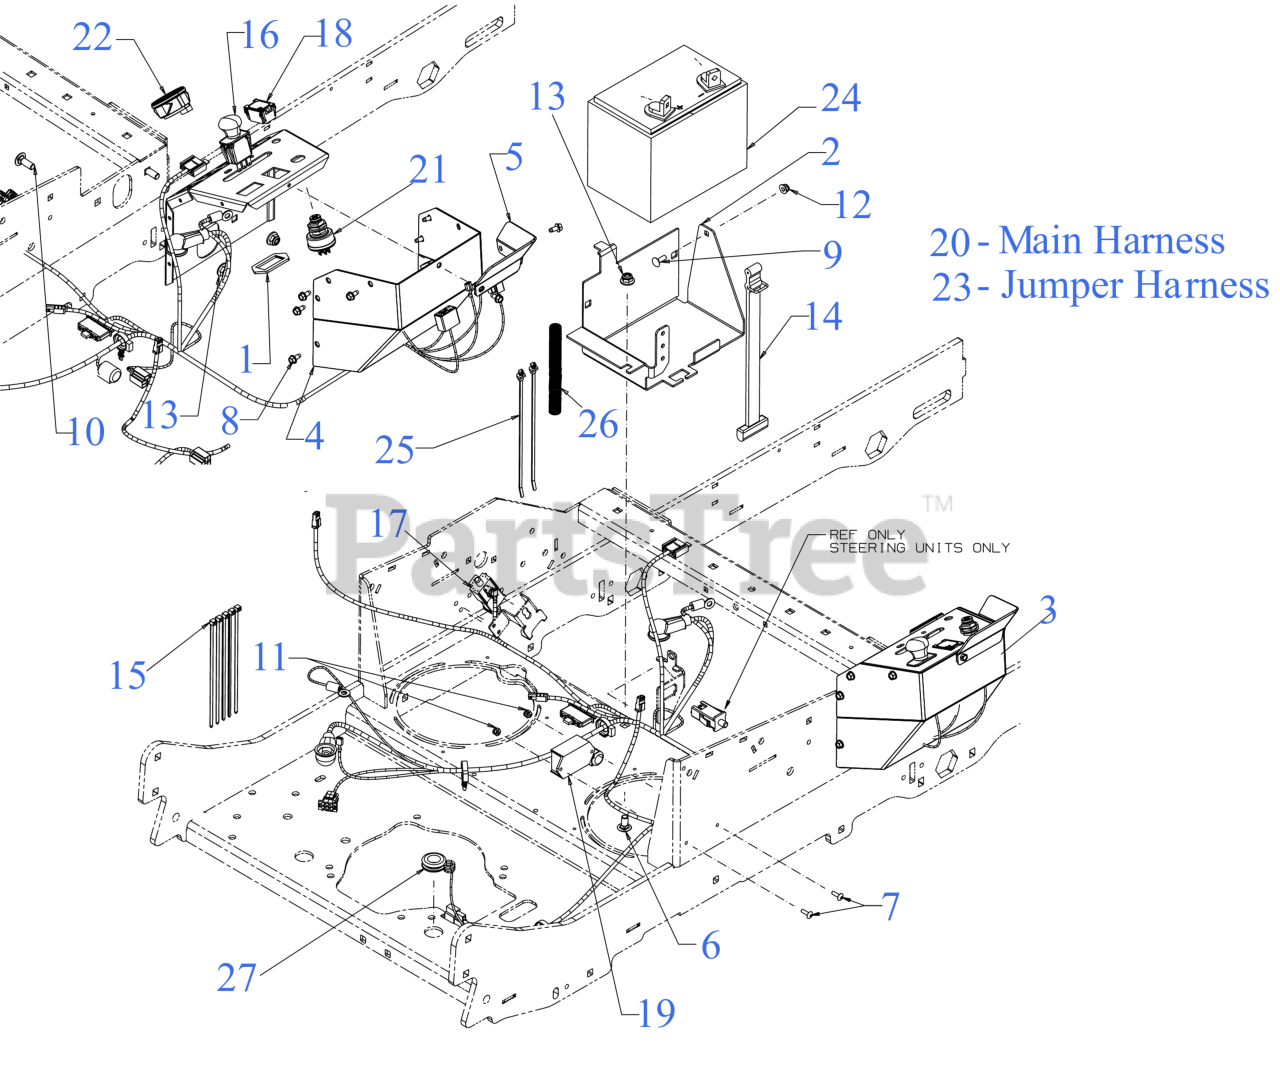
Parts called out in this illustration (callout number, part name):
1	BRACKET-PTO SWITCH
2	BATTERY MOUNTING BRACKET
3	CONTROL POD - RH
6	CARRIAGE BOLT 3/8-16 x .750 GR5
7	SCREW #10-24 x .62
8	SCREW 1/4-20 X.500
9	SCREW 1/4-20 x .75 GR5
10	CARRIAGE BOLT 3/8-16 x 1.00 GR5
12	FLANGE LOCK NUT
14	BATTERY RETAINER STRAP
15	7" CABLE TIE
16	PTO SWITCH (BLACK KNOB) TEXT SYM
17	3 POLE SWITCH ( NC-NO-NO)
19	CONTROL PANEL (SOFT CLUTCH)
20	WIRE HARNESS ASSEMBLY (KOH/KAW EFI)
21	KEY SWITCH (3 POSITION)
21	PRO-Z KEY SET
22	DUAL FUEL GAUGE
23	JUMPER HARNESS (W/RELAY)
23	12V RELAY 35A
24	BATTERY (230 CCA AGM U1-280)
25	CABLE TIE
26	CONVOLUTED CONDUIT 1"
27	RUBBER GROMMET
